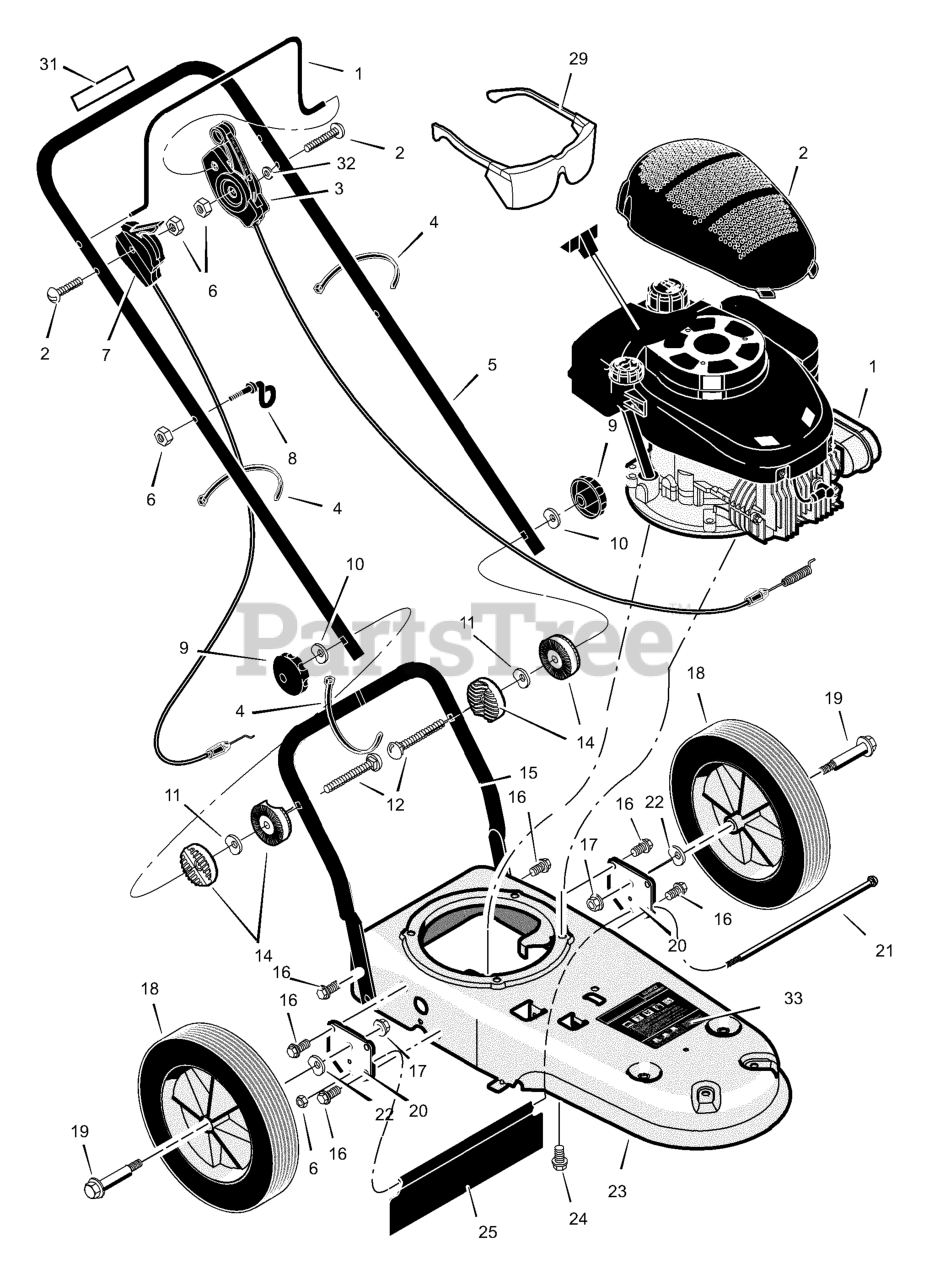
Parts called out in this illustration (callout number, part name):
1	Lever, Stop
3	Cable, Control Latching
4	Tie, Cable
5	Handle
7	Control, Throttle
8	Guide, Rope
9	Knob, Handle
10	Washer
11	Washer, Spring
14	Pivot, Handle
15	Handle, Lower
17	Nut, Axle
18	Wheel & Tire
19	Bolt, Axle
20	Bracket, Wheel
21	Bolt, Carriage
22	Washer, Spring
23	Frame, Trimmer
24	Bolt
25	Shield, Trailing
26	Bolt
28	Engine *
29	Protection, Eye
30	Nut
32	Spacer
33	Decal, Warning
